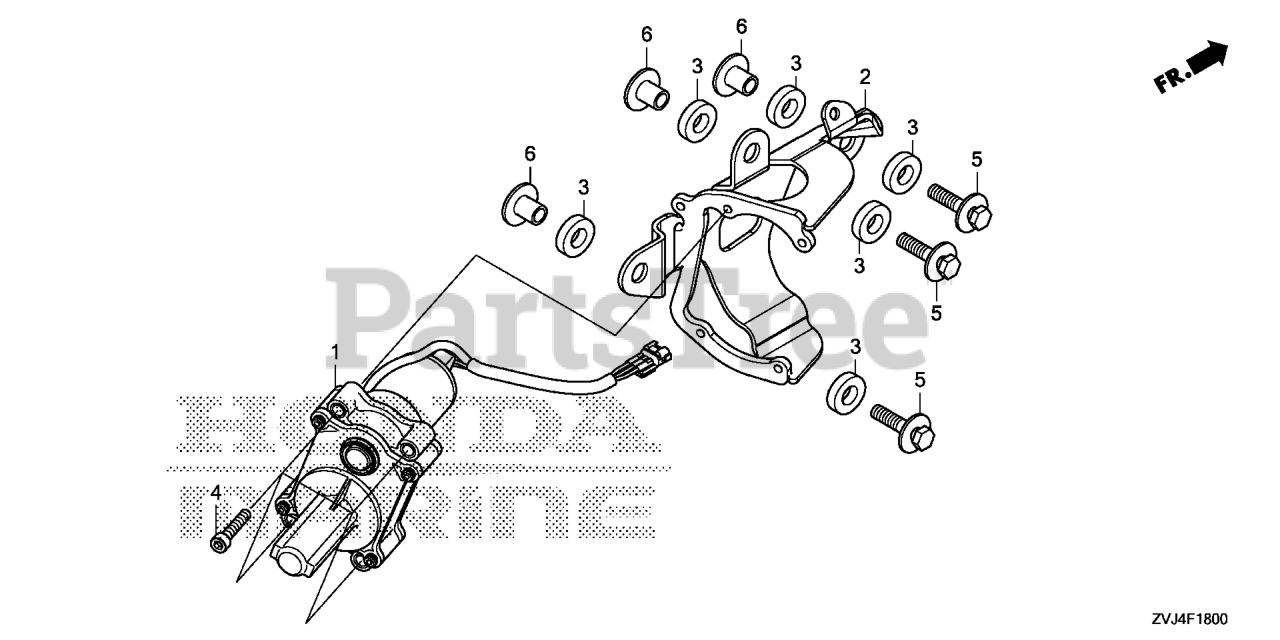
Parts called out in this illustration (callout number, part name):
1	ACTUATOR ASSY., SHIFT
2	BRACKET, SHIFT ACTUATOR
3	RUBBER, CUSHION
4	BOLT, SOCKET (6X30)
5	BOLT-WASHER (8X35)
6	COLLAR (8.5X14.5)
